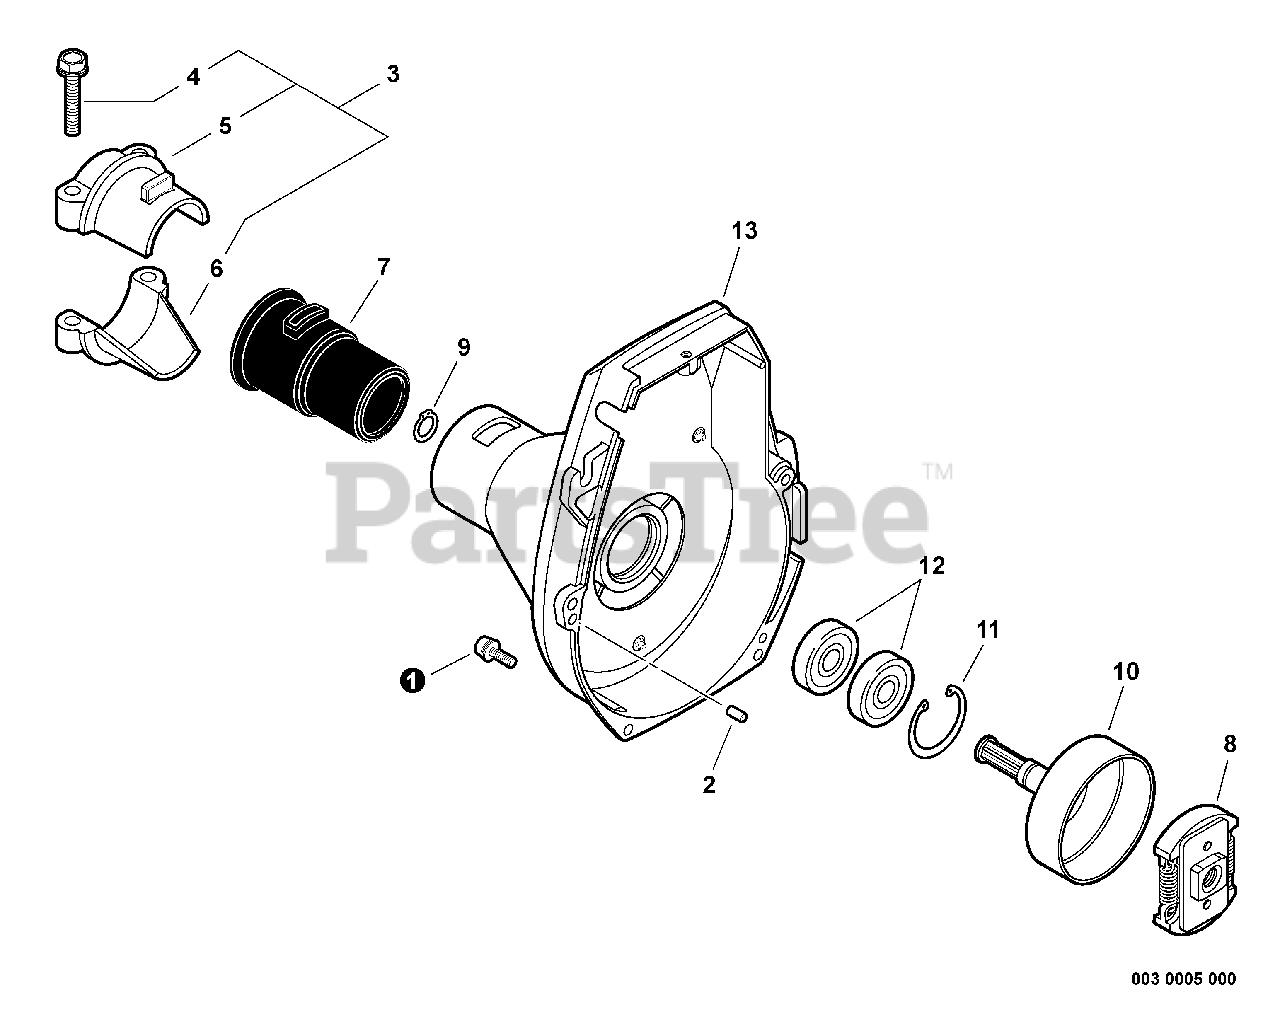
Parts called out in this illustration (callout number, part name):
1	SCREW - 4X16
2	PIN - LOCATING
3	MAIN PIPE CLAMP KIT
4	BOLT - 5X25
5	CLAMP, MAIN PIPE - UPPER
6	CLAMP, MAIN PIPE - LOWER
8	CLUTCH ASSY
9	RING, RETAINING - 12
10	DRUM, CLUTCH
11	RING, RETAINING - 28
12	BEARING, BALL - 6001
13	CASE, FAN
